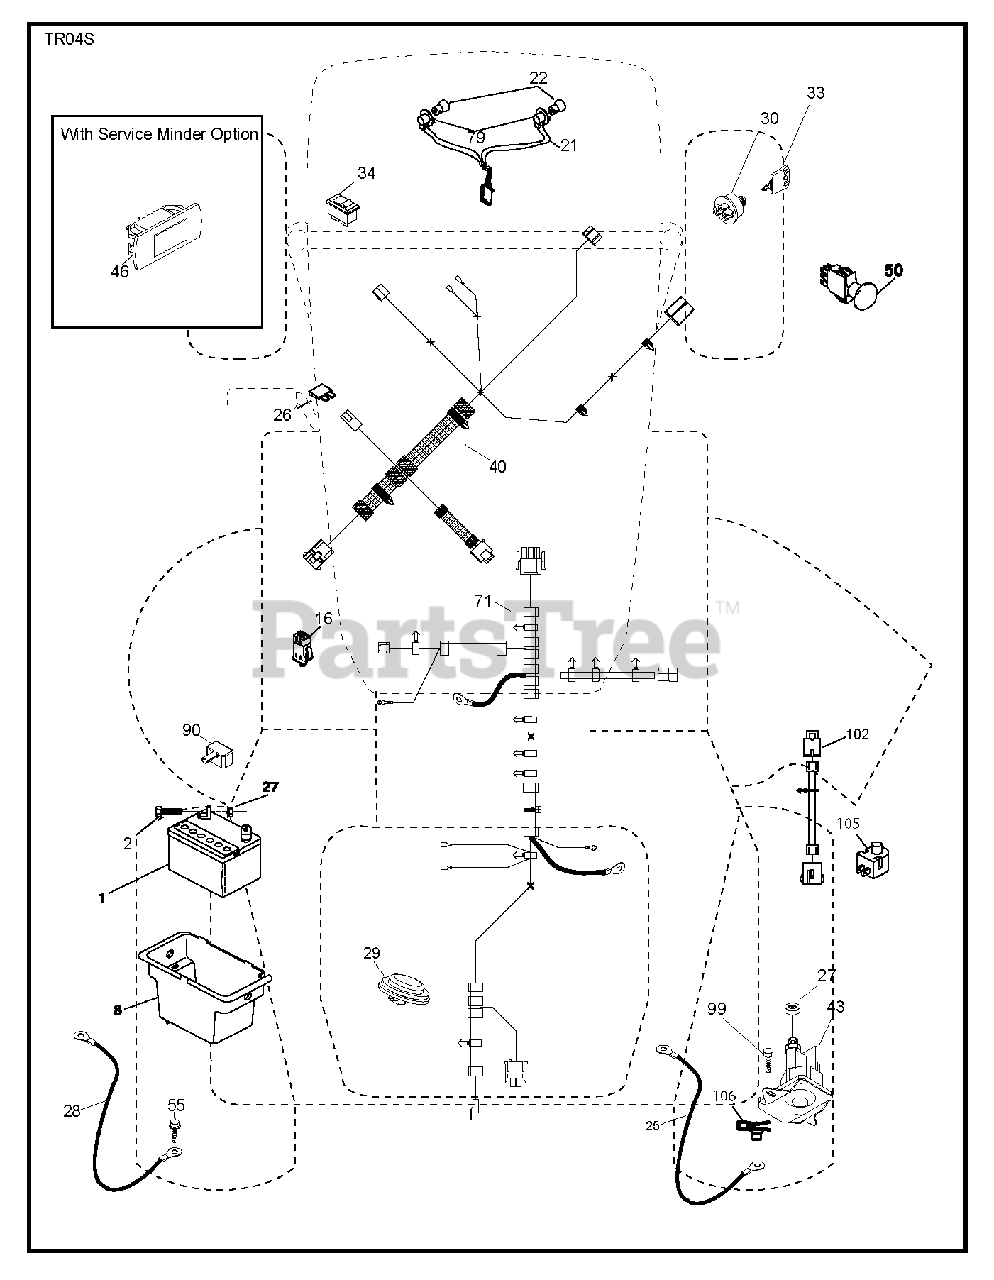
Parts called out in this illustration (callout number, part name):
1	Battery, Dry 30 Amp
2	BOLT.HEX.1/4.X.3/4.DICHROMATE
8	BOX.BATTERY.MNT.REAR.L
16	SWITCH INTERLOOK PUSH-IN
21	HARNESS.LIGHT W/4152J BULBS
25	CABLE.BATT.RED.8GA.17
26	FUSE 20AMP
27	NUT
28	CABLE.GROUND.REAR.BATTERY.8G
29	SWITCH.SEAT.DELTA.OPC.
30	SWITCH.IGN.DELTA.W.LGH.ROS
33	KEY.CHAIN.BLISTER.PACK.GEN.INT
40	HARNESS.TEX.DASH.ELEC.REAR BAT
43	SOLENOID.W/BRASS.PLUNGER
46	RP GUAGE.SRVCMNDR.HRMTR.
50	RB PTO.SWITCH.8 TERMINAL.BLACK
55	SCREW 5/16"
71	HARNESS.TEX.CHSSIS.REAR.BATT
79	BULB HOLDER ASM.
90	COVER.TERMINAL.BATTERY
99	SCREW HEXWSHR 1/4-20X3/4
102	HARNESS PIGTAIL PCH TEX ROS
105	REVERSE SWITCH
106	1/4-20 U NUT
